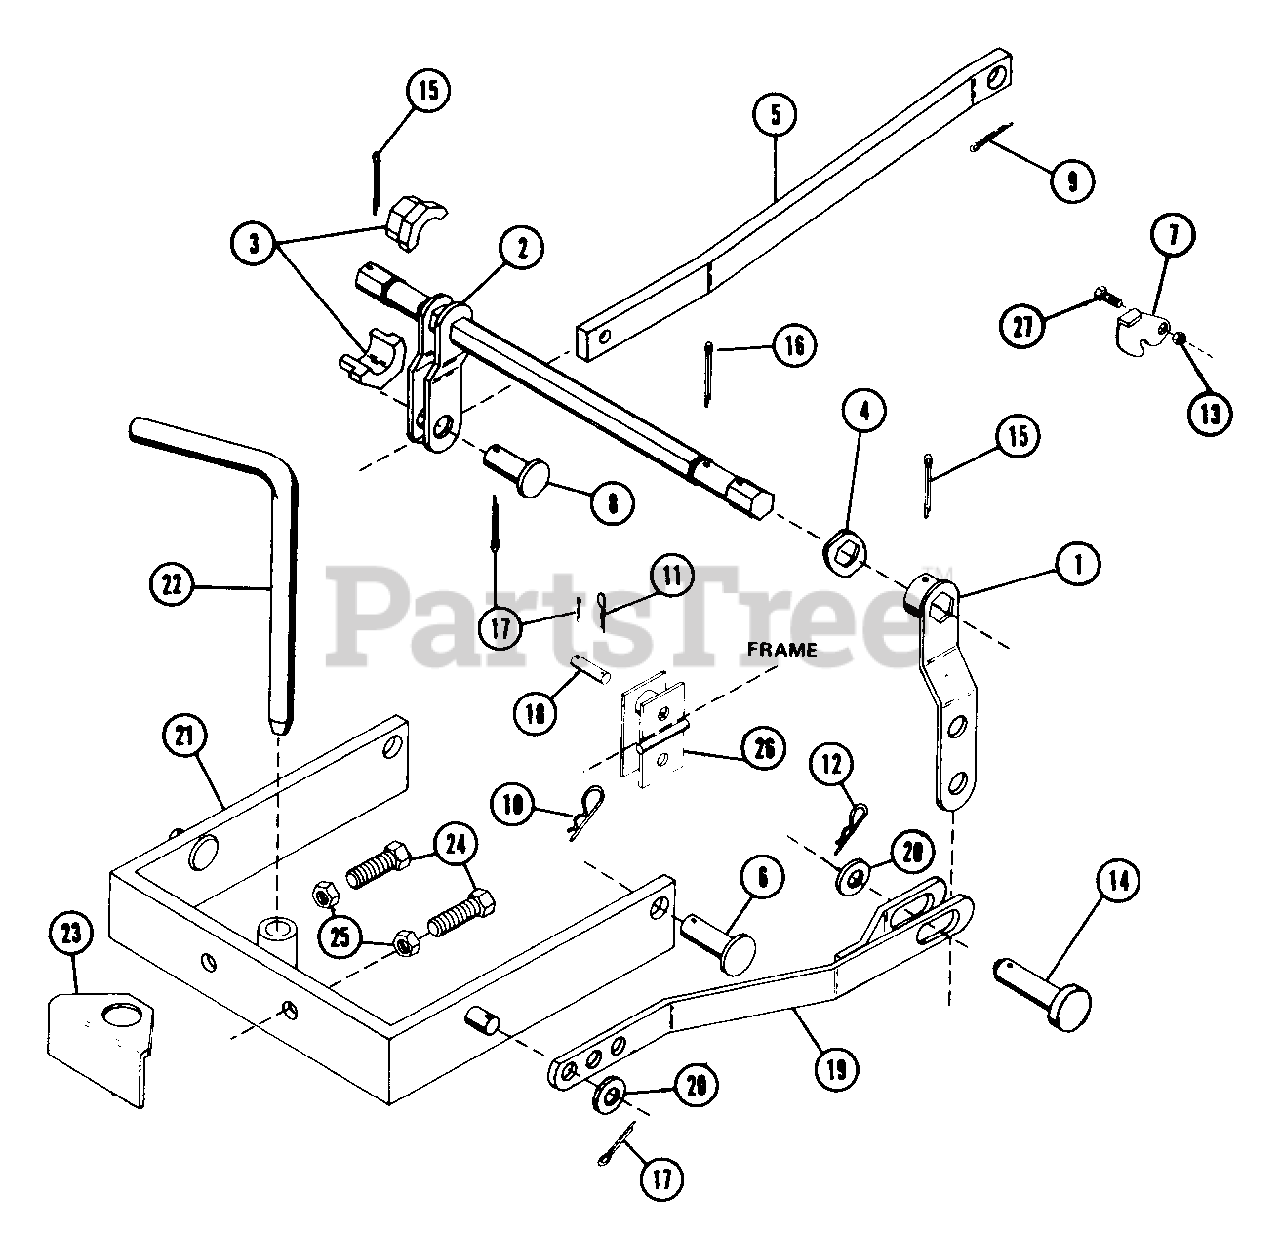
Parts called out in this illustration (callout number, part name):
3	BSHG-FLG 1.000X1.750X1.000
4	WSHR-FL-STL 1.031X1.875X.060
5	LIFT LINK
6	CLEVIS PIN
8	CLEVIS PIN
9	PIN-COTR .09X1.87 PL
10	PIN-HAIR INT .09X.62X2.25
11	PIN-HAIR INT .14X.4X2.75
12	PIN-HAIR INT .09X1.88 PL
13	NUT-LK-CTR .375-16 GR A PL
14	CLEVIS PIN
15	PIN-COTR .18X2.0 ZCC
16	PIN-COTR .18X1.50 PL
17	PIN-COTR .12X1.0 PL
19	LIFT STRAP
20	WSHR-FL-STL .531X1.062X.095 PL
21	HITCH BAIL ASSEMBLY
22	HITCH PIN
23	STABILIZER PLATE
24	BLT-HEX .62-11X2.25 GR2
25	NUT-HEX .625-11
26	ADAPTER HITCH PIVOT
27	BLT-HEX .38-16X.75 PL GR2
